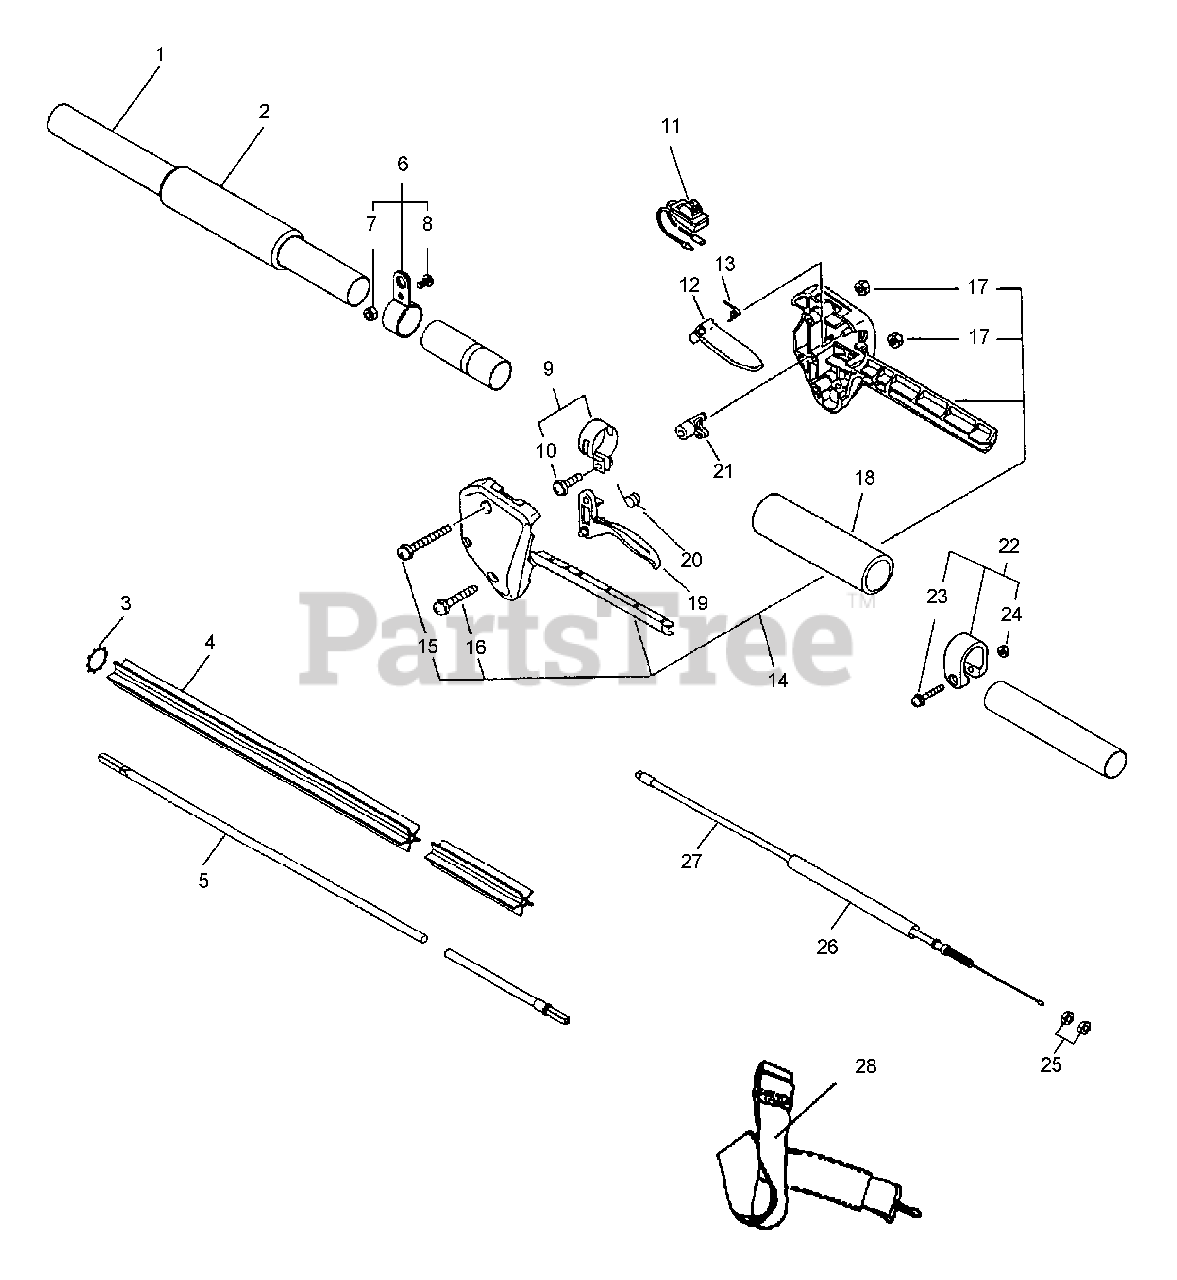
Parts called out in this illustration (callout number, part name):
1	MAIN PIPE ASSY
2	GRIP, FRONT - LEFT
3	LOCKWASHER - EXTERNAL
4	LINER - FLEXIBLE
5	DRIVESHAFT - FLEXIBLE
6	HANGER KIT
7	LOCKNUT - 10-24
8	SCREW
9	CLAMP KIT
10	SCREW - 5X14
11	IGNITION SWITCH ASSY
12	LEVER, TRIGGER LOCKOUT
13	SPRING, LOCKOUT LEVER
14	CONTROL HANDLE KIT
15	SCREW - 5X35
16	SCREW - 5X25
18	GRIP, HANDLE
19	TRIGGER, THROTTLE
20	SPRING, TRIGGER
21	LOCKOUT, THROTTLE
22	CLAMP KIT
23	SCREW - 5X28
26	TUBE - VINYL
27	CABLE, THROTTLE
28	SHOULDER STRAP ASSY
